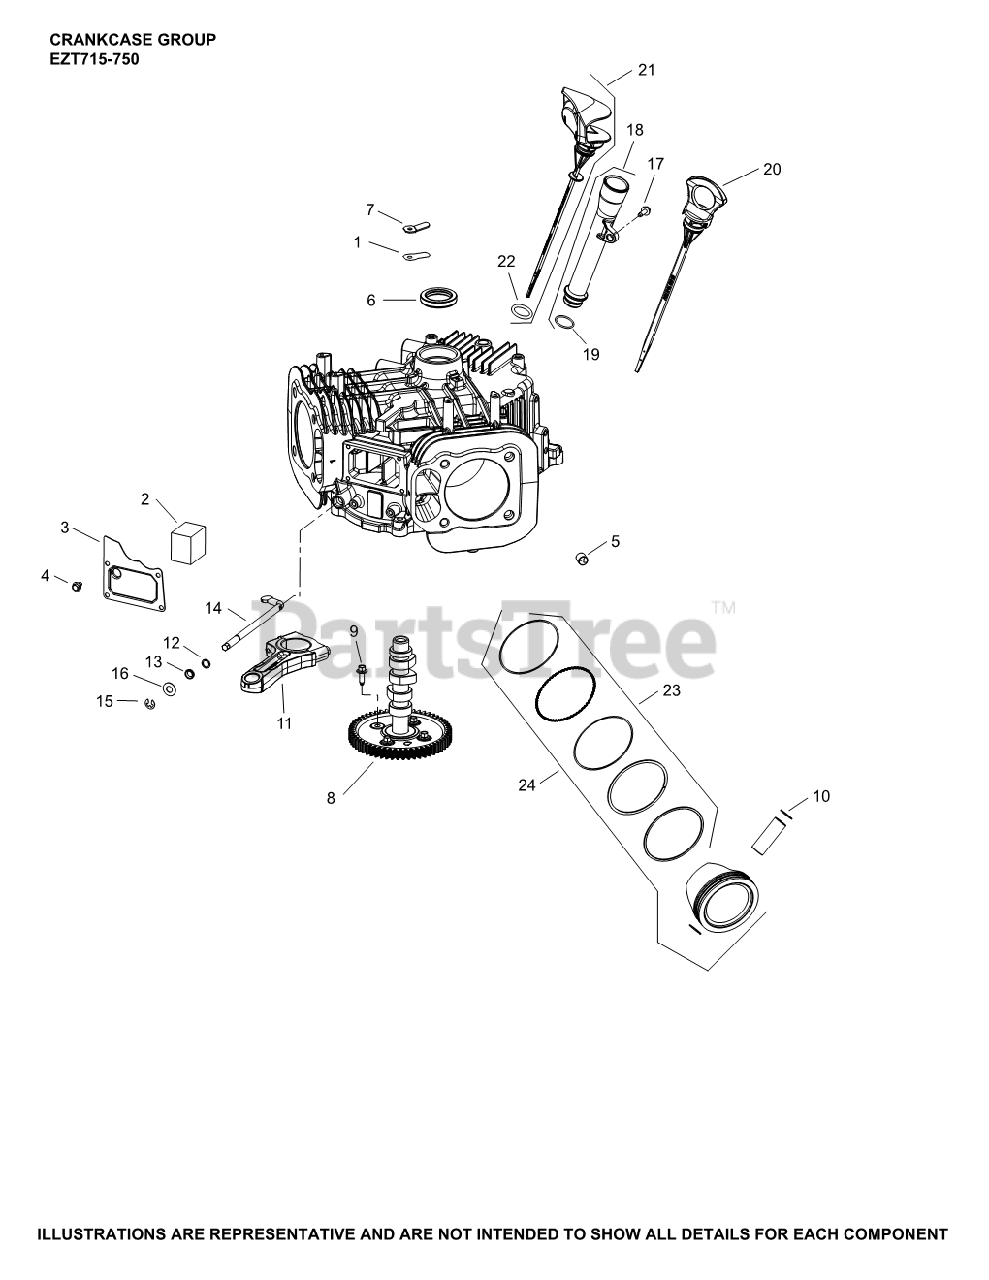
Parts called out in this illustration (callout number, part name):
1	REED, BREATHER
2	FILTER, BREATHER
3	COVER, BREATHER MEDIA
4	SCREW, THREAD FORMING
5	PIN, LOCATING
6	SEAL, OIL (HELIX LIP)
7	RETAINER, REED
8	CAMSHAFT ASSEMBLY
10	RETAINER, PISTON PIN
11	KIT, CONNECTING ROD ASSEMBLY USE 25 067 04-S
11	KIT, CONNECTING ROD ASSEMBLY (.25 mm)
12	WASHER, FLAT 11/32"
13	SEAL, GOVERNOR CROSS SHAFT
14	KIT, CROSS SHAFT
15	CLIP, RETAINER GOVERNOR SHAFT
16	WASHER, FLAT 9 MM
17	SCREW, THREAD FORMING
18	TUBE ASSEMBLY, OIL FILL
21	DIPSTICK ASSEMBLY
23	RING SET(STD)STYLE B-1.2mm Tp RING THICK
23	RING SET(.08)STYLE B-1.2mm Tp RING THICK
23	RING SET(.25)STYLE B-1.2mm Tp RING THICK
23	RING SET(.50)STYLE B-1.2mm Tp RING THICK
24	PISTON W/RINGS (STYLE B)(STD) - RING SET 25 108 01-S
24	PISTON W/RINGS (STYLE B)(.08) - RING SET 25 108 02-S
24	PISTON W/RINGS (STYLE B)(.25) - RING SET 25 108 03-S
24	PISTON W/RINGS (STYLE B)(.50) - RING SET 25 108 04-S
